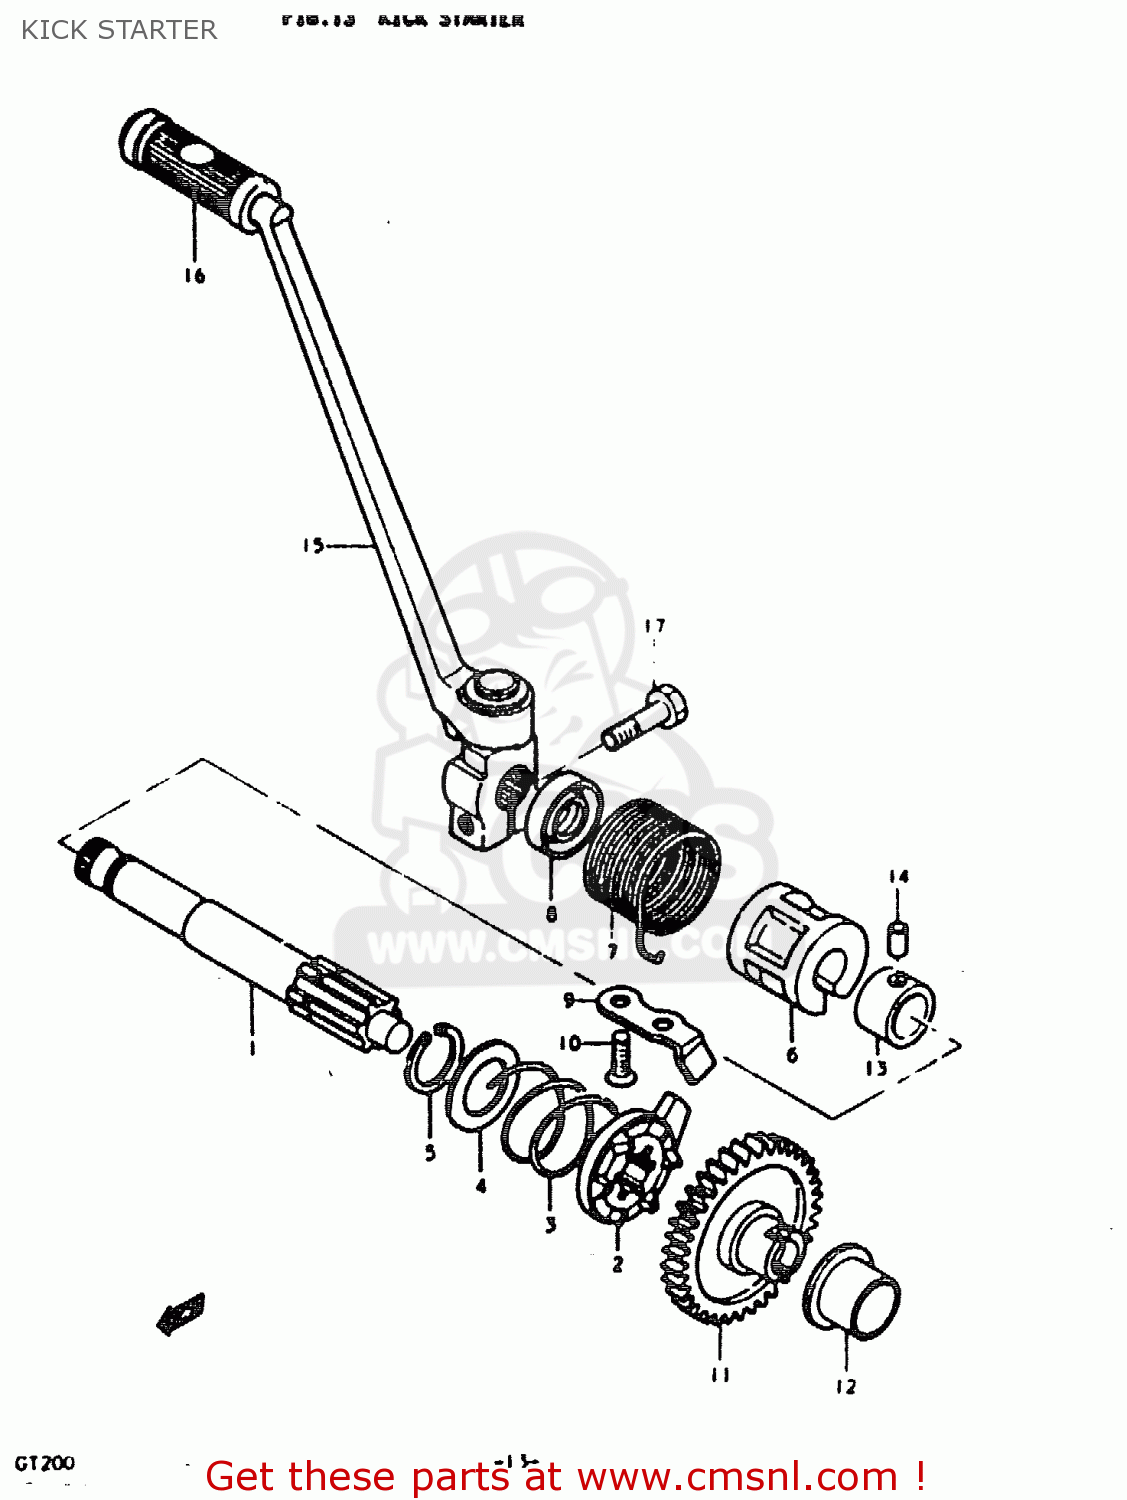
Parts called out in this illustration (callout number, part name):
1	SHAFT, KICK STARTER
2	STARTER,KICK
3	SPRING
4	PLATE
5	CIRCLIP
6	GUIDE,KICK SHAFT SPRING
7	SPRING
8	SEAL,OIL(16X30X8)
9	GUIDE,KICK STARTER
10	SCREW
11	GEAR, KICK STARTER DRIVE
12	BUSHING
13	BUSHING
14	PIN
15	LEVER ASSY,KICK STARTER
16	RUBBER,KICK STARTER PEDAL
17	BOLT
